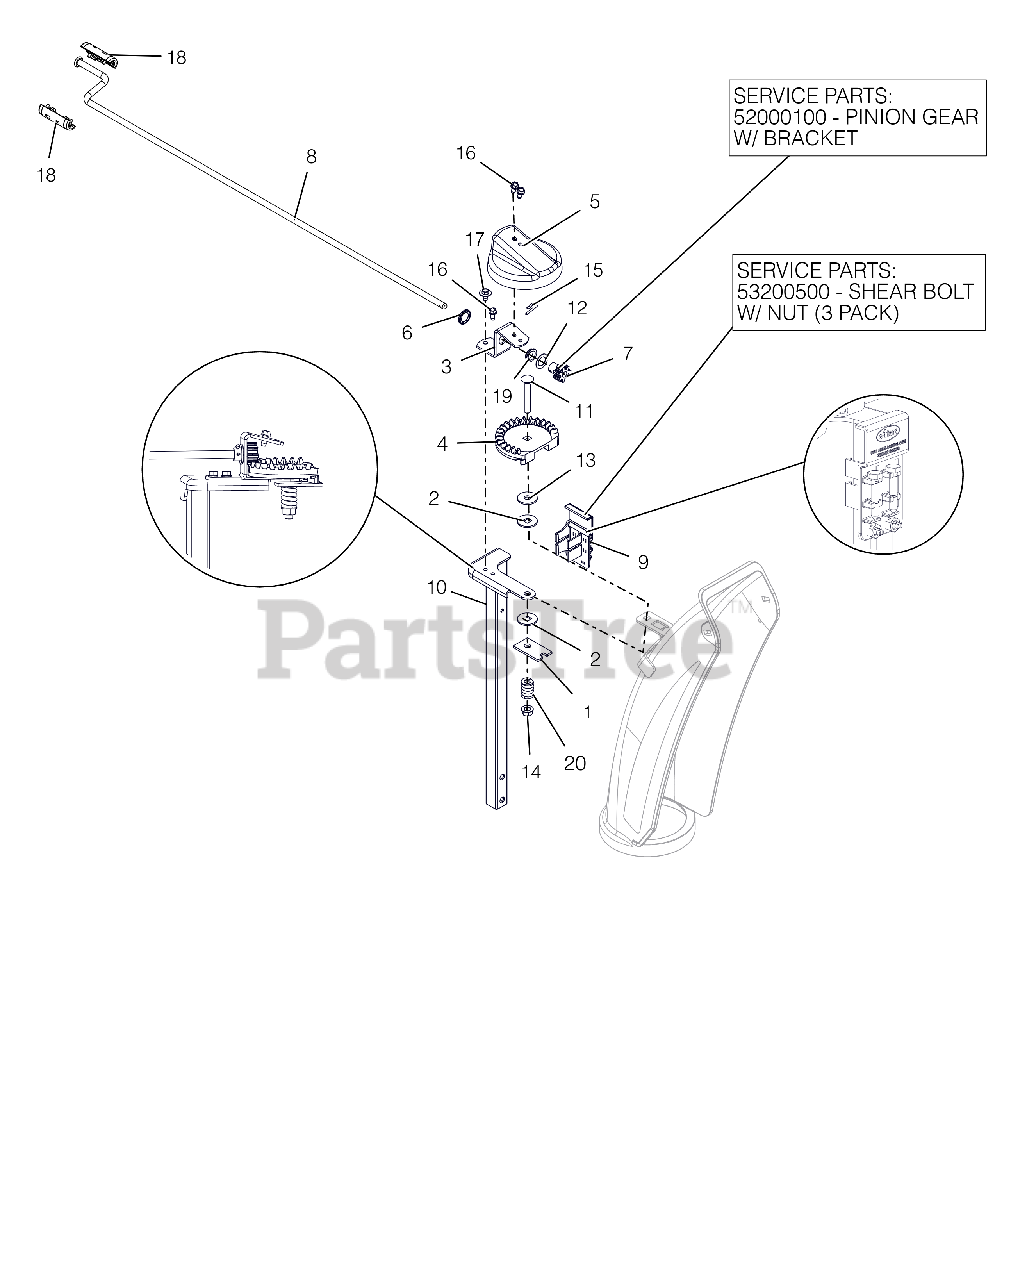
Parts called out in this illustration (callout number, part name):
1	PLATE, FRICTION
2	FRICTION WASHER
3	BRACKET, PINION GEAR
4	CHUTE GEAR
5	GEAR COVER
6	PUSHNUT .625
7	PINION GEAR - CHUTE
7	PINION GEAR W/BRACKET
8	ROD, CHUTE CRANK, COMP&SNOTEK
9	HOLDER W SMALL SHEAR BOLT /NUT
9	SHEAR BOLT WITH NUT
10	CHUTE PEDESTAL, TALL COMPACT
11	@BLT-RDHDSQNK .38-16X2.50 G5YZ
12	WSHR-THRST .625 X 1.0 X .03
13	@WSHR-FL-STL .406X1.25X.10 ZC
14	@NUT-LK-TOP-FLG .38-16 YWZC
15	PIN, SPRING CLIP
16	SCR-TAP .25-20X.50 HWH TR YWZ
17	SCR-TAP .25-20X.50 LGHWH TR YZ
18	KNOB, CHUTE CRANK - SNAP BLK
19	BUSHING, POLYLINER-.63 SNAPIN
20	SG-COMP .187X.56X1.62
